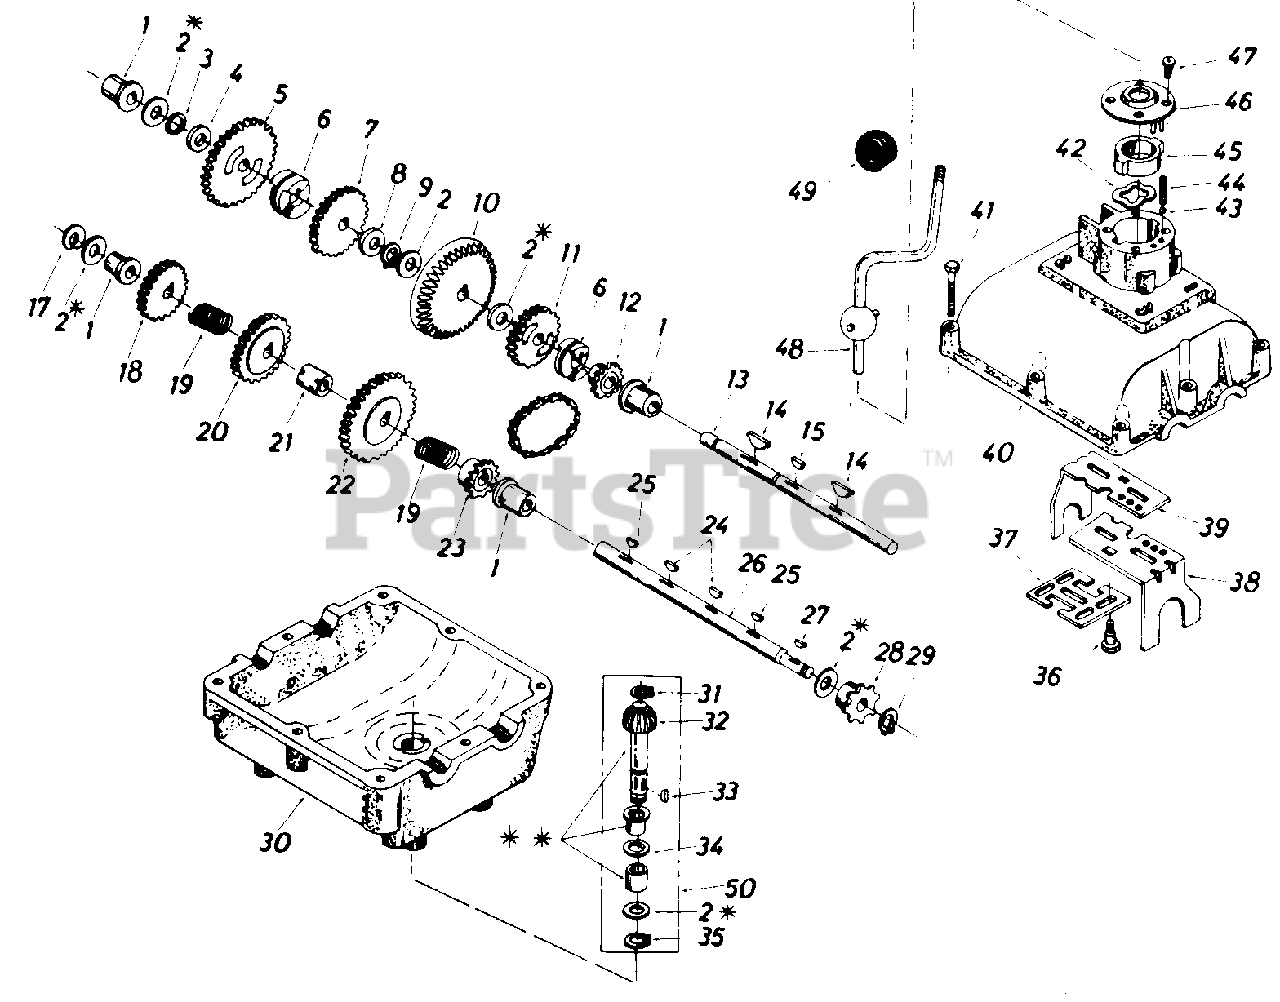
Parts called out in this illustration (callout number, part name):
1	Bearing, Flange
2	Washer, Plain (.040)
3	Ring, Retaining
4	Spacer
5	Assembly, Gear, Kit, 30T
6	Collar, Clutch
7	Assembly, Gear, Kit, 25T
8	Spacer
9	Ring, Retaining
10	Gear, Bevel, 42T
11	Gear, Spur, 20T
12	Sprocket, Special, 12T
13	Shaft, Drive
14	Key, Hi-Pro, Special
15	Key, Wdrf., #9
17	Ring, Retaining
18	Gear, Spur, 20T
19	Spring, Compression
20	Assembly, Gear, Kit, 25T
21	Spacer
22	Gear, Spur, 30T
23	Sprocket, 12T
24	Key, #16 Wdrf., Alloy
25	Key, #3 Wdrf., Alloy
26	Shaft, Output
27	Key, #4 Wdrf., Alloy
28	Sprocket, 7T
29	Ring, Retaining
30	Housing, Lower
31	Ring, Retaining
32	Pinion, Bevel, 16T
33	Key, Wdrf., #4
34	O-Ring
35	Ring, Retaining
36	Screw, Shoulder
37	Plate, Lock-Out
38	Fork, Shifter, L.H.
39	Fork, Shifter, R.H.
40	Housing, Upper
41	Bolt, Hx. Hd. S.T., 1/4-20 x 1-5/16
42	Washer, Wave
43	Ball, Detent
44	Spring, Detent
45	Insert, Nylon
46	Cover, Nylon
47	Screw, Tapping, #10-24
48	Assembly, Lever, Shift
49	Knob, Shift
50	Assembly, Kit, Input Shaft
